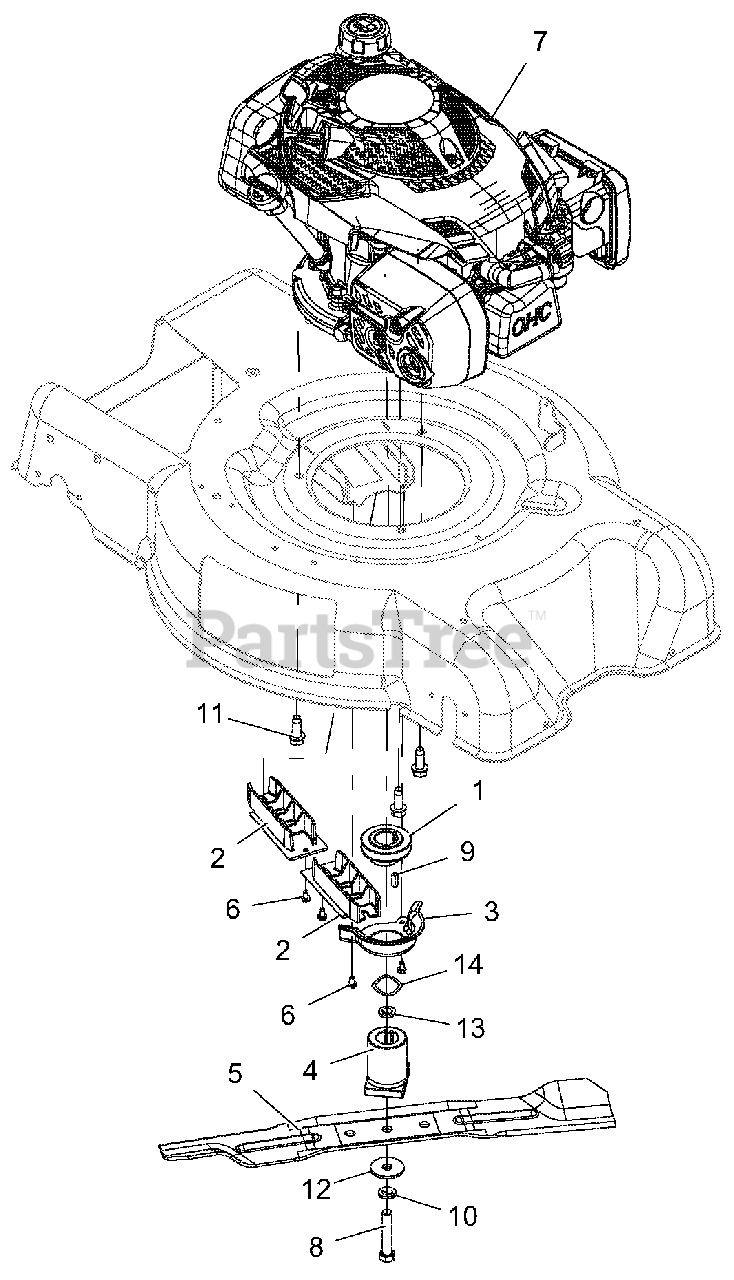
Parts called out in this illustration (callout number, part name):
1	PULLEY, GROUND DRIVE, LM
2	GUIDE, BELT - INNER
3	GUIDE, BELT CRANKSHAFT
4	ADAPTOR, BLADE
5	BLADE, MOWER 21" HIGH-LIFT
6	SCR, TAP 10-24 x .375 PRE-COAT 80
7	ENGINE, SUBARU
8	BLT-HEX .44-20 x 2.25 GR8 YWZC
9	KEY-SQ .188 x .188 x .625
10	WSHR-LK .44 x .109 REG YWZC
11	SCR-TAP .38-16 x 1.00 HWH TR YZ
12	WSHR-FL-STL .4375 x 1.50 x .125 YWZC
13	WSHR-FL-STL .459 x .750 x .105 YWZC
14	WASHER, WAVE
